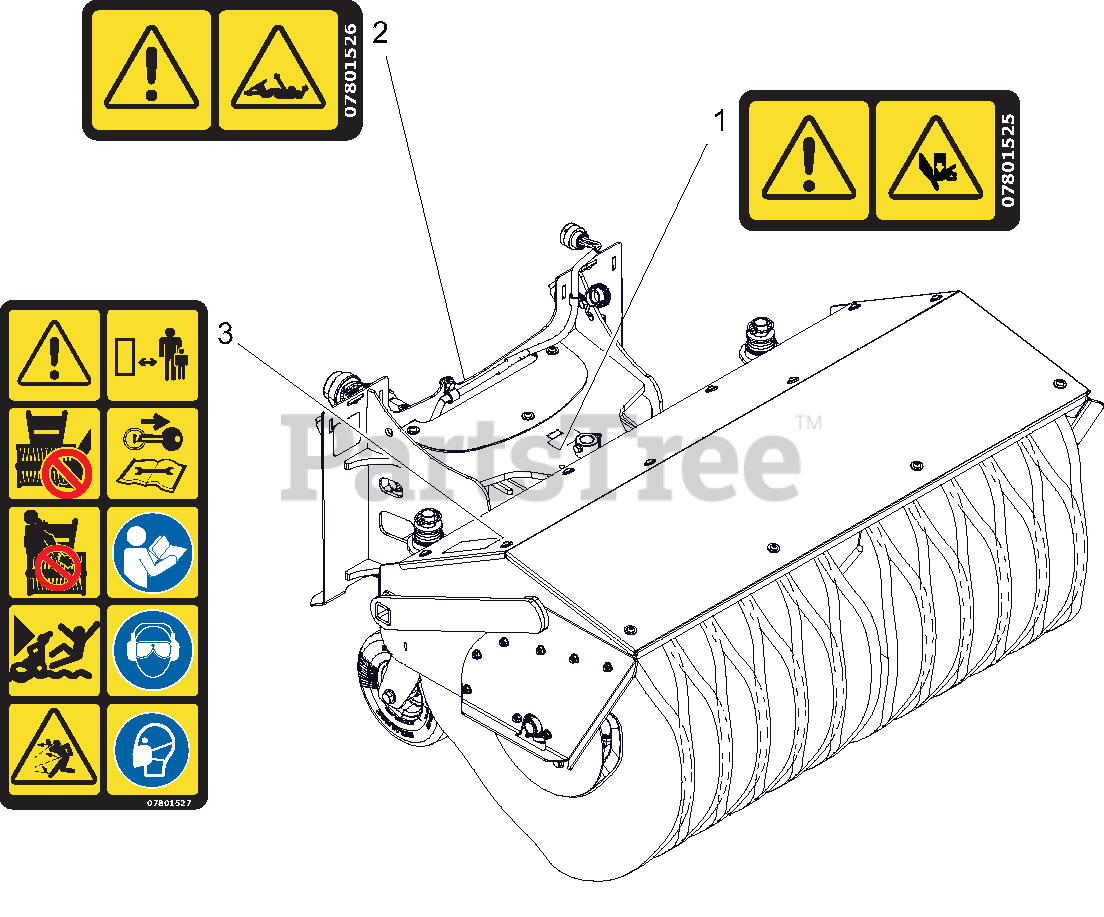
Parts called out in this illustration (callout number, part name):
1	DECAL, SAFETY - PINCH POINT
2	DECAL- SAFETY - ROTATING SHAFT
3	DECAL, SAFETY - BRUSH HOUSING
